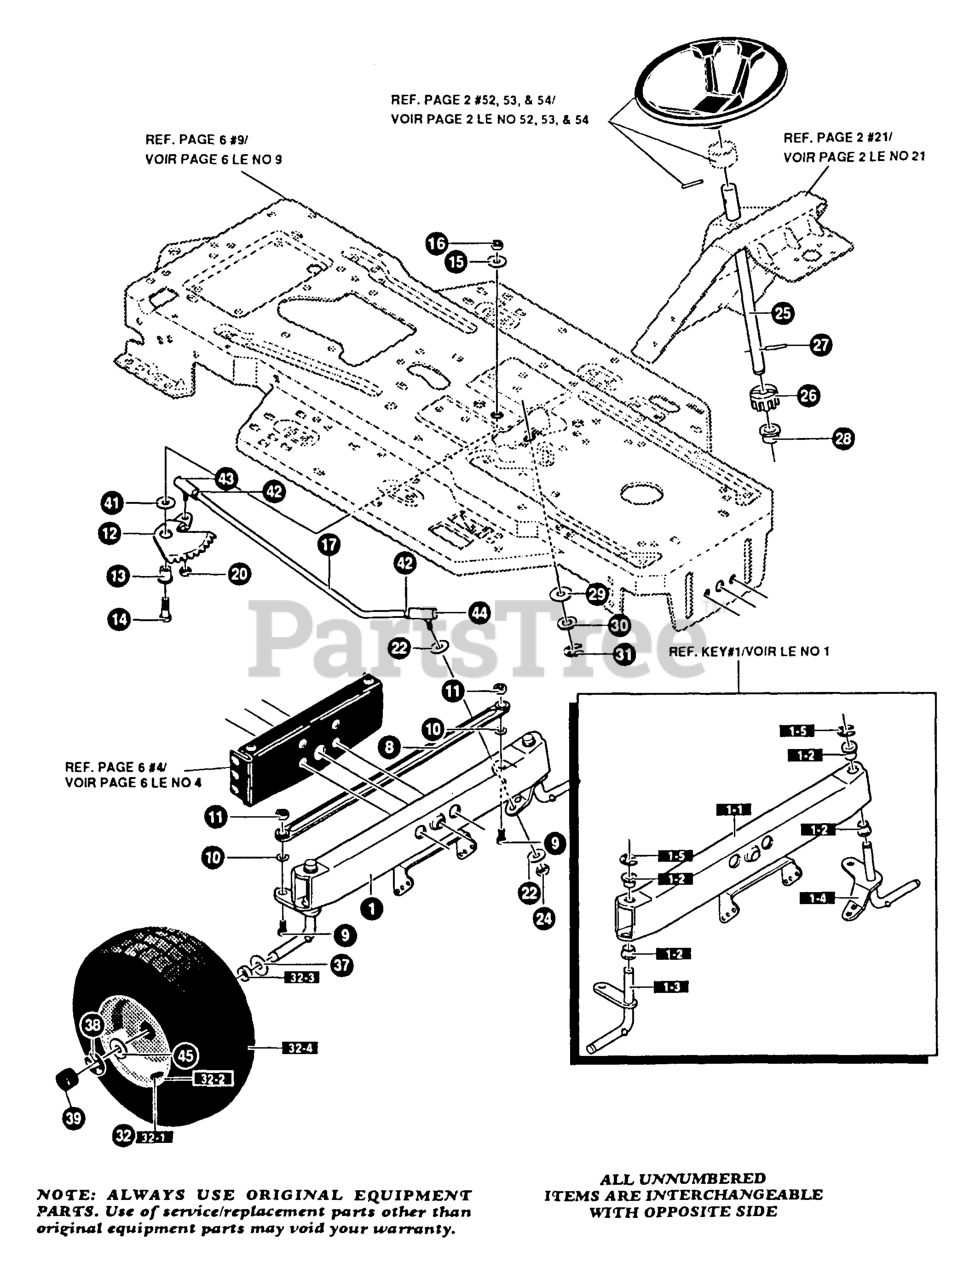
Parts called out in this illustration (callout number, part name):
1	AXLE, FRONT ASSY
1-1	FRONT AXLE
1-2	SPINDLE BEARING
1-3	ASSY, SPINDLE, RH
1-4	ASSY, SPINDLE, LH
1-5	RING, RETEX
8	TIE ROD ASSY
10	WASHER
11	NUT
12	SECTOR, STEER
13	BEARING
17	STEERING LINK
22	WASHER
25	SHAFT, STEERING
26	PINION, STEER
27	PIN,DOWEL
28	BEARING
30	WASHER
31	RING, RETEX
32	TIRE & RIM
32-1	VALVE STEM
32-2	RIM, WHEEL
32-3	BEARING
37	WASHER
38	RING, RETEX
39	HUB CAP
41	WASHER
43	BALL JOINT
44	BALL JOINT
